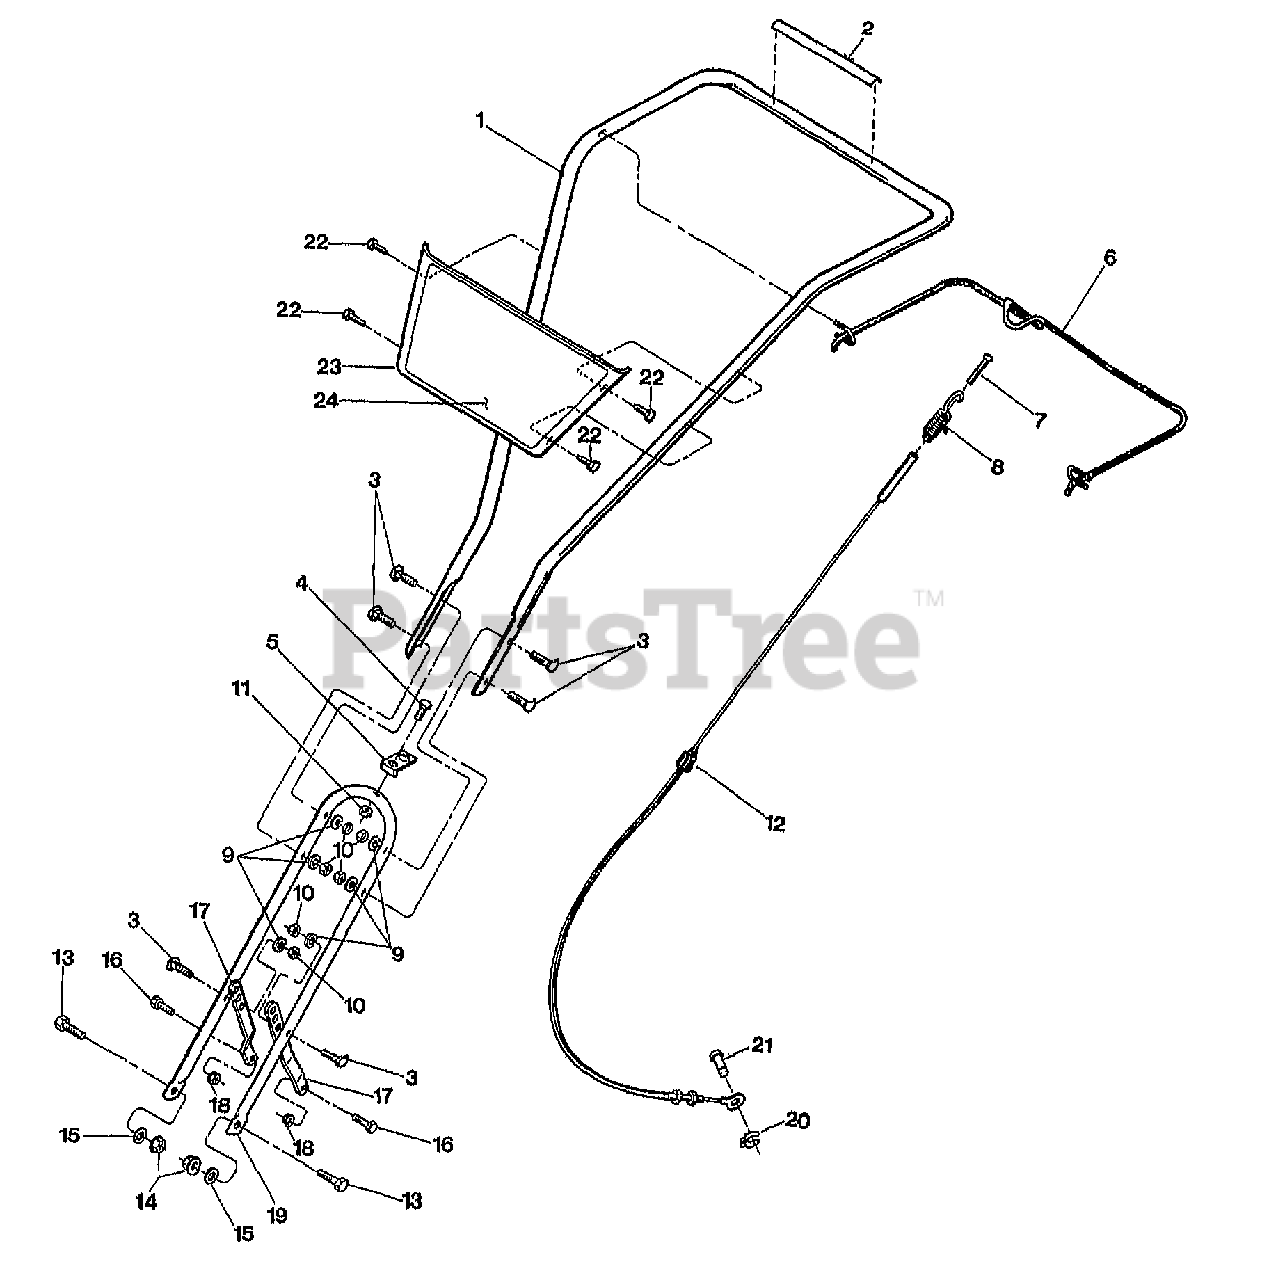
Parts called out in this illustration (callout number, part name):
1	HANDLEBAR-UPR W/DECAL
2	DECAL-55103
3	SCR-CUR.H.5/16X1 1/2
4	SCR-HH 1/4-20X1.25
5	TAB-CONDUIT MOUNT
6	BAIL-FWD. DRIVE PNT
7	SCR-SLOT.H.10-24X2
8	ASSM-SPRING CABLE
9	WASHER-LK .312 ZP
10	NUT-HEX 5/16-18 ZP
11	NUT-LK 1/4-20
12	ASSM-CONTROL CABLE
13	SCR-HH 3/8-16X.75 G5 ZP
14	NUT-LOCK 3/8-16 NYLON ZP
15	WASHER-FLAT 3/8 SAE
16	SCR-HHC 5/16-18X.75 GR 5 ZP
17	LINK-H/BAR PNT
18	NUT-H/LK 5/16-18
19	HANDLEBAR-LWR PNT
20	RING-KLIP .188 DIA
21	PIN-CLEVIS CABLE
22	SCR-HWH 1/4-20 X .5 STH
23	PANEL-55102 PNT
24	DECAL-GRAPHICS PANEL TUFFY (MODEL NAME & LOGO)
